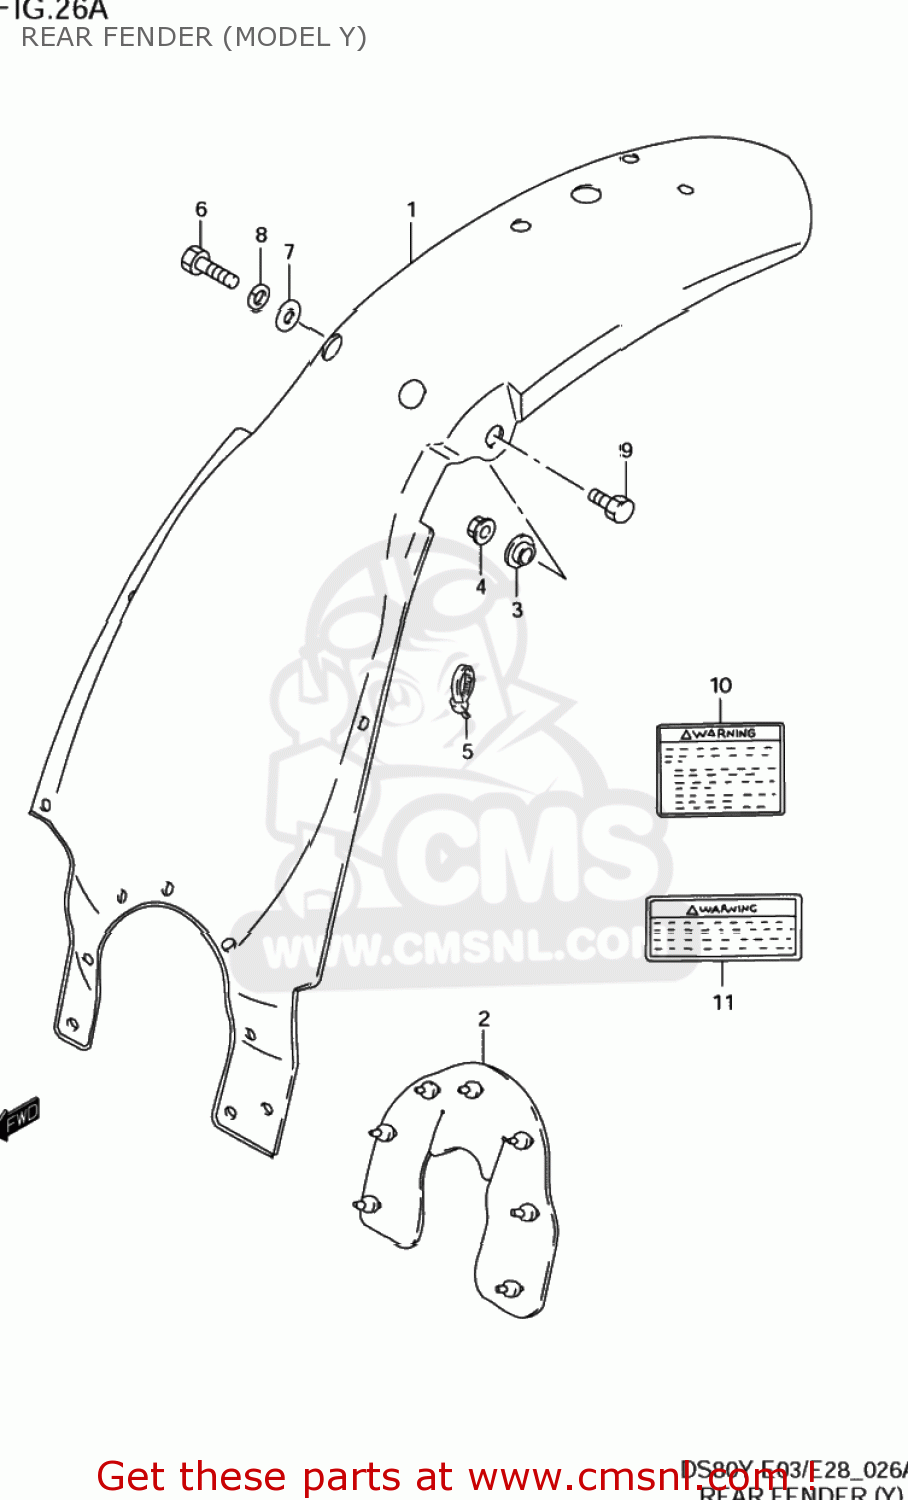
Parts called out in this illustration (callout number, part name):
1	FENDER,RR
2	MUDGUARD,RR FENDER
3	WASHER
4	NUT
5	CLAMP(L:250)
6	BOLT
7	WASHER(8.5X28X1.6)
8	LOCK WASHER
9	BOLT
10	LABEL (GENERAL WARNING)
11	LABEL (MANUAL NOTICE)
12	MANUAL,OWNER'S DS80Y
